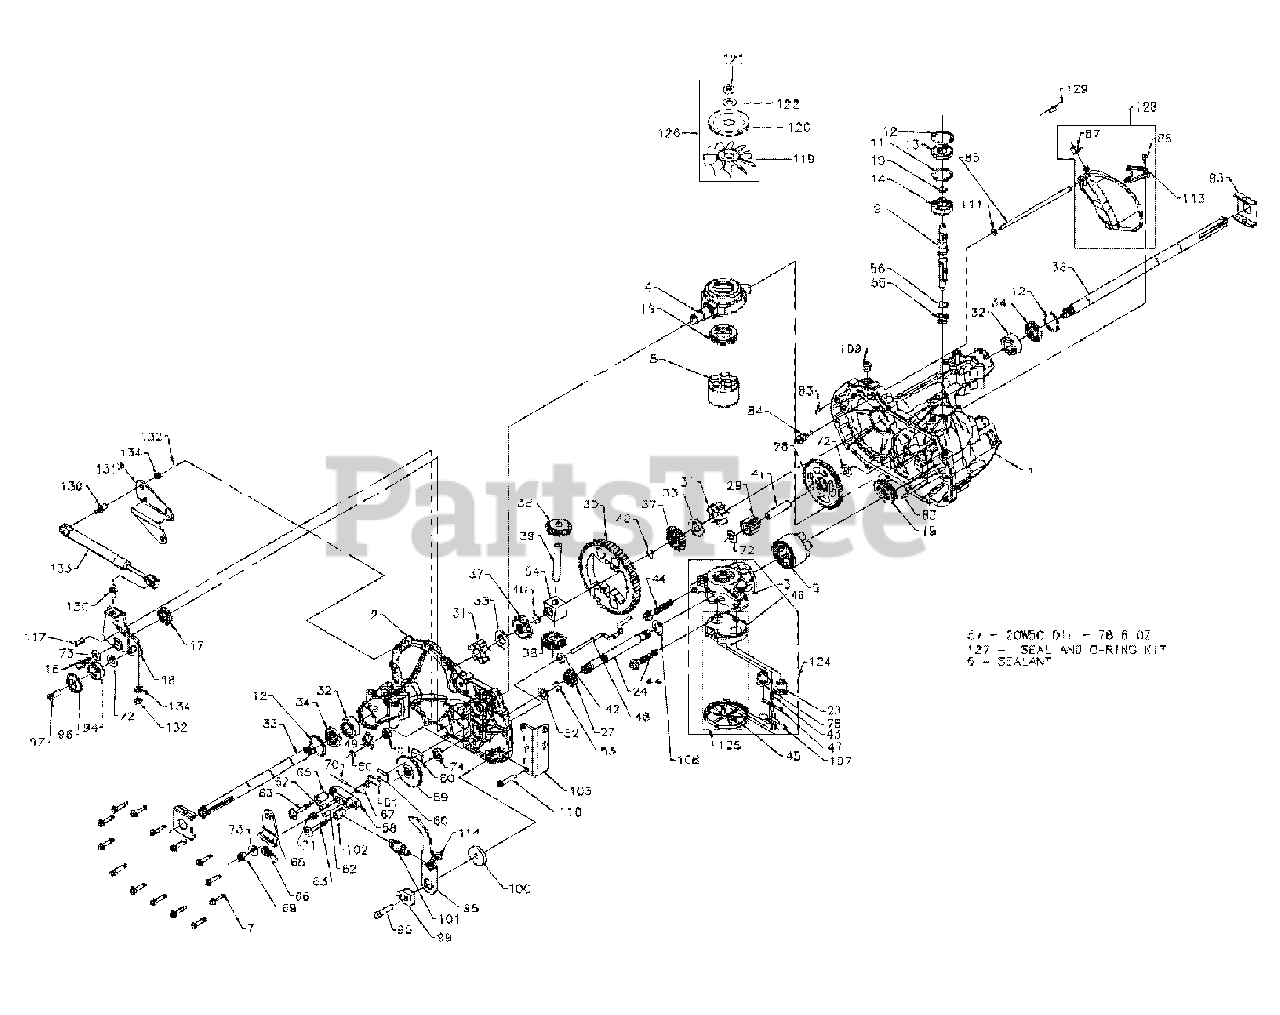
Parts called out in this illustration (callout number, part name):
1	Main Housing, Assembly
2	Side Housing, Assembly
3	Center Section, Assembly
4	Swashplate, trunnion Machined
5	Block, Assembly
6	Sealant
7	Hex Flange Screw .25-20 x 1.25
9	Shaft, Input
10	Ring, Retaining
11	Spacer
12	Ring, Retaining
13	Seal, Lip .67 x 1.58 x .276
14	Ball Bearing 17MM I.D. x 40MM O.D. 12MM
16	Hex Flange Head Screw .313-24 x .75
17	Lip Seal .18 x .32 x 7
18	Arm Control
19	Bearing , Thrust .30 x .52 x .13
23	Washer, Check Plug Assembly
24	Shaft, Motor
27	Gear, Pinnion 13T
28	10T/48T Gear
29	Gear, 10T Jackshaft
30	60T Bull Gear
31	Sleeve Bearing .75 x 1.75 x .825
32	Sleave Bearing (Outboard) .75 x 1.575 x .625
33	Washer .75 x 1.50 13 THK
34	Lip Seal Axle Seal
35	Shaft, Axle .75 x 11.39 (Key Right Hand)
36	Shaft, Axle .75 x 11.39 (Key Left Hand)
37	Miter Gear (Splined)
38	Miter Gear 15T
39	Shaft
40	Ring, Spiral Retaining
41	Pin, Jackshaft
42	Magnet, Ring
43	Spring, Bypass
44	Hydro Mounting Screw .38-24 x 2.5 Ling
45	Filter
46	Base, Filter
47	Actuator, Bypass
48	Rod, Bypass Actuator
49	Arm, Bypass
50	Retaing Ring .25 External
51	Seal, Lip .741 x .25 x .25 TC
52	Washer, Flat .625 I.D. x 1.00 O.D. x .05 THK
53	Retaining Ring
54	Bearing, Center Block
55	Spring, Helical Compression
57	20W-50 Oil
58	Brake Yoke
59	Rotor, Brake
60	Brake Puck
61	Puck Plate
62	Brake Actuating Pin
63	HFHCS .25-20 x with Patch, Special Flange
65	Spacer
66	Spring, Brake Arm Bias
67	Square Head Bolt .313-24 Ribbed
68	Arm Brake
69	Slotted Hex Nut .313-24
70	Cotter Pin .094 x .75
71	Compression Spring Brake Anti-Drag
72	Washer, HT .50 I.D. x 1.00 O.D. x .032
73	Washer, Flat .34 I.D. x .875 O.D.
74	Oil Seal .825 x 1.00 x .25
75	Check Plug Assembly, .027 Washer
83	Pin, Standard Headless
84	Fitting, .316 SAE .157 Tube
85	Hose, Expansion Tank
87	Cap, Vent
88	Bolt, Self tapping 10-32 x .50
93	Spring Clip, Housing Thrust
94	Bearing, Ball .62 x I.D. x 1.38 x .44
95	Screw Socket Head Cap .313-24 x 1.50
96	Spacer, Location
97	Screw SFHCS .313-18 x 1.00
98	Arm, Return
99	Puck, Adjusting
100	Washer .24 I.D. x 1.80 O.D. x .239
101	Spring, Extension
102	Spacer .25 I.D. .55 O.D. x .87
103	Bracket, Torque
107	Deflector
108	Washer, Motor Shaft .71 I.D. x 1.15 O.D. x .03
109	Plug SAE #6
110	Screw, Torx Head .313-18
111	O-Ring .103 x .299 I.D.
113	Bracket, Support Expansion Tank
114	Spring Guid
117	Pin, Spring
119	Fan, 7 inch
120	Pulley
121	Hex Lock Nut .50-20 (Nylon Insert)
122	Washer, O.D. Slotted .53 x 1.63 x .06
123	Bracket, Belt Keeper
124	Center Section, Filter, Bypass Assembly
125	Filter Assembly
126	Kit, Fan/Pulley
127	Seal, O-Ring Kit
128	Kit, Expansion Tank
129	Cap, Expansion tank Shipping
130	Stud, Ball
131	Bracket, Crusie Damper
132	Hex Nut .313-18
133	Damper
134	Washer, Helical Spring Lock .313, Regular
